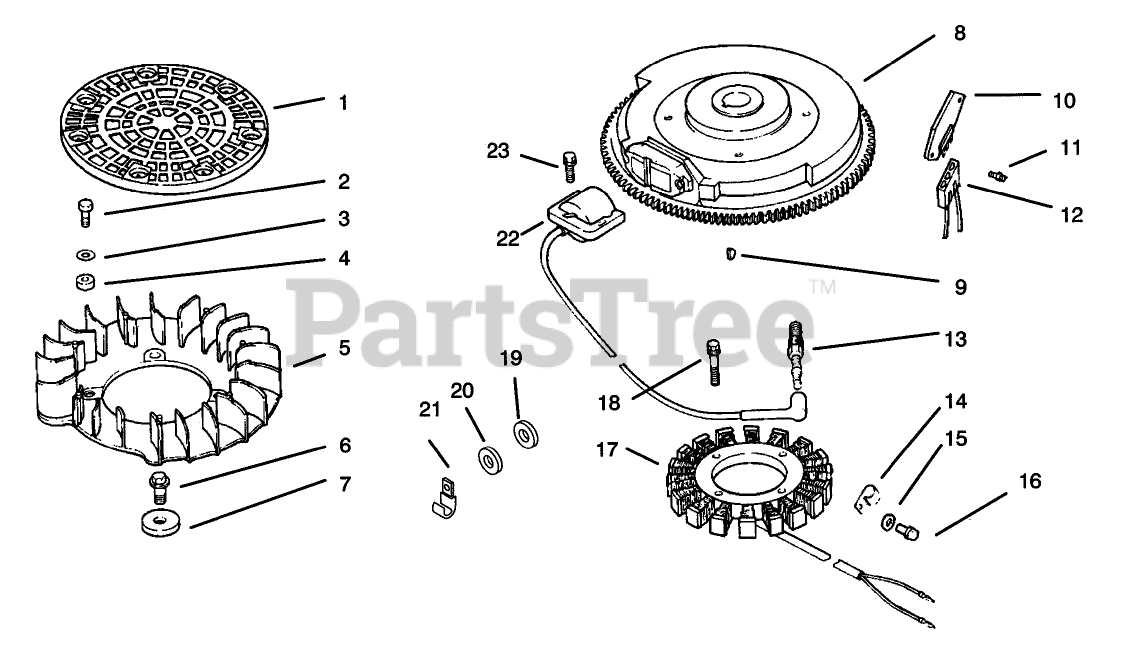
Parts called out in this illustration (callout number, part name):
1	Screen-Grass (Only On: 72103, 72083)
2	Screw
3	Washer
4	Spacer-Fan (Only On: 72103)
5	Fan (Only On: 72103, 72083)
6	Screw
7	Spacer-Fan
8	Flywheel ASM (Only On: 72103, 72083)
9	Key
10	Rectifier-Regulator
11	Screw
12	Connector
13	Spark Plug
14	Clip
15	Washer
16	Screw
17	Stator-15 amp
18	Screw
19	Washer
20	Washer
21	Clip
22	Module-Ignition
23	Screw
